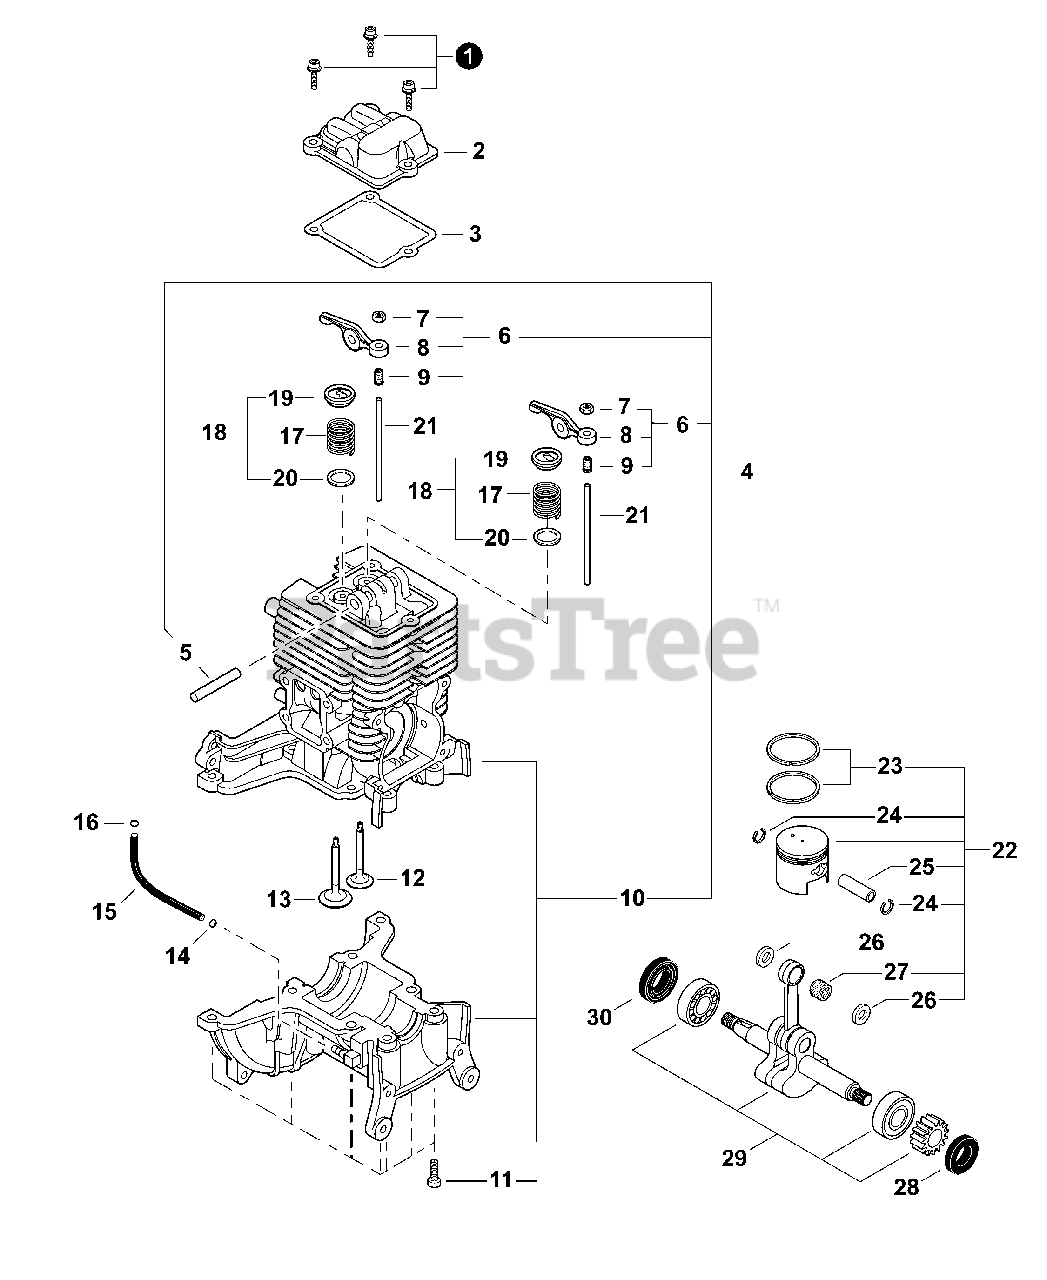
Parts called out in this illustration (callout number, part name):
1	BOLT M4×14
2	COVER, ROCKER ARM
3	GASKET, ROCKER ARM
4	ENGINE BLOCK ASSY
5	SHAFT, ROCKER ARM Ø5×37.8 MM
6	ARM ASSY, ROCKER
7	NUT, ADJUSTER LOCK 5
8	ARM, ROCKER
9	SCREW, ADJUSTER
10	ENGINE BLOCK
11	BOLT 5×16
12	VALVE, EXHAUST
13	VALVE, INTAKE
14	CLIP Ø6
15	PIPE, IMPULSE 3×6×87
17	SPRING, VALVE
18	RETAINER SET, VALVE
19	RETAINER, VALVE
20	WASHER, VALVE 9
21	PUSHROD
22	PISTON KIT
23	RING, PISTON
24	RING, SNAP
25	PIN, PISTON 10
26	WASHER, THRUST 10
27	BEARING, NEEDLE 10
28	SEAL, OIL 12
29	CRANKSHAFT ASSY
30	SEAL, OIL 12
